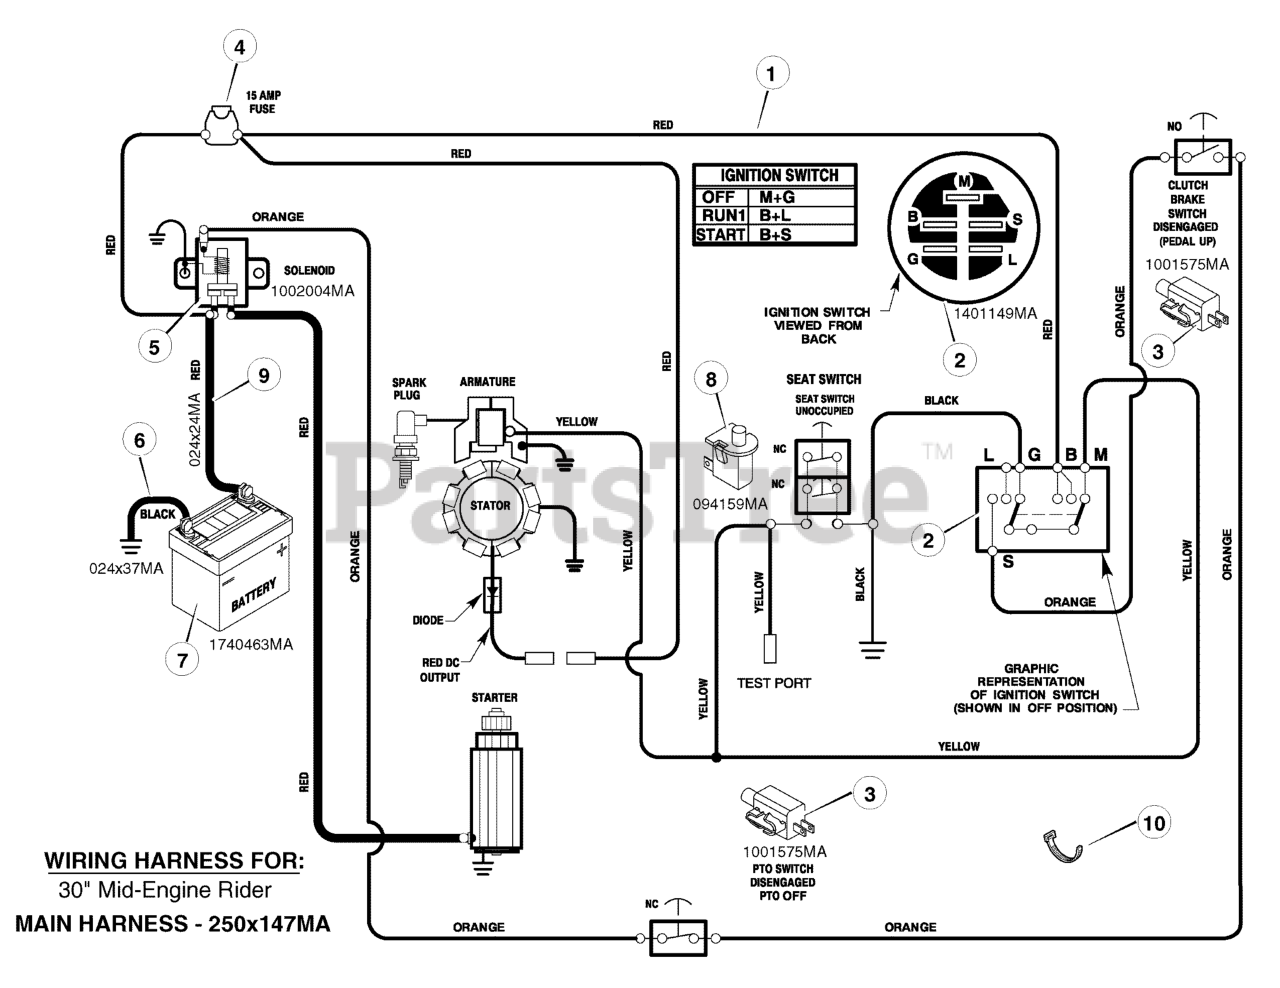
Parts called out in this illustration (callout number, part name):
1	HARNESS, Chassis Wire
2	SWITCH, Ignition
3	SWITCH, Limit
5	SOLENOID
6	CABLE, Battery Ground
8	SWITCH, Seat Sensor
9	CABLE, Red Battery
10	Strap, Tie
